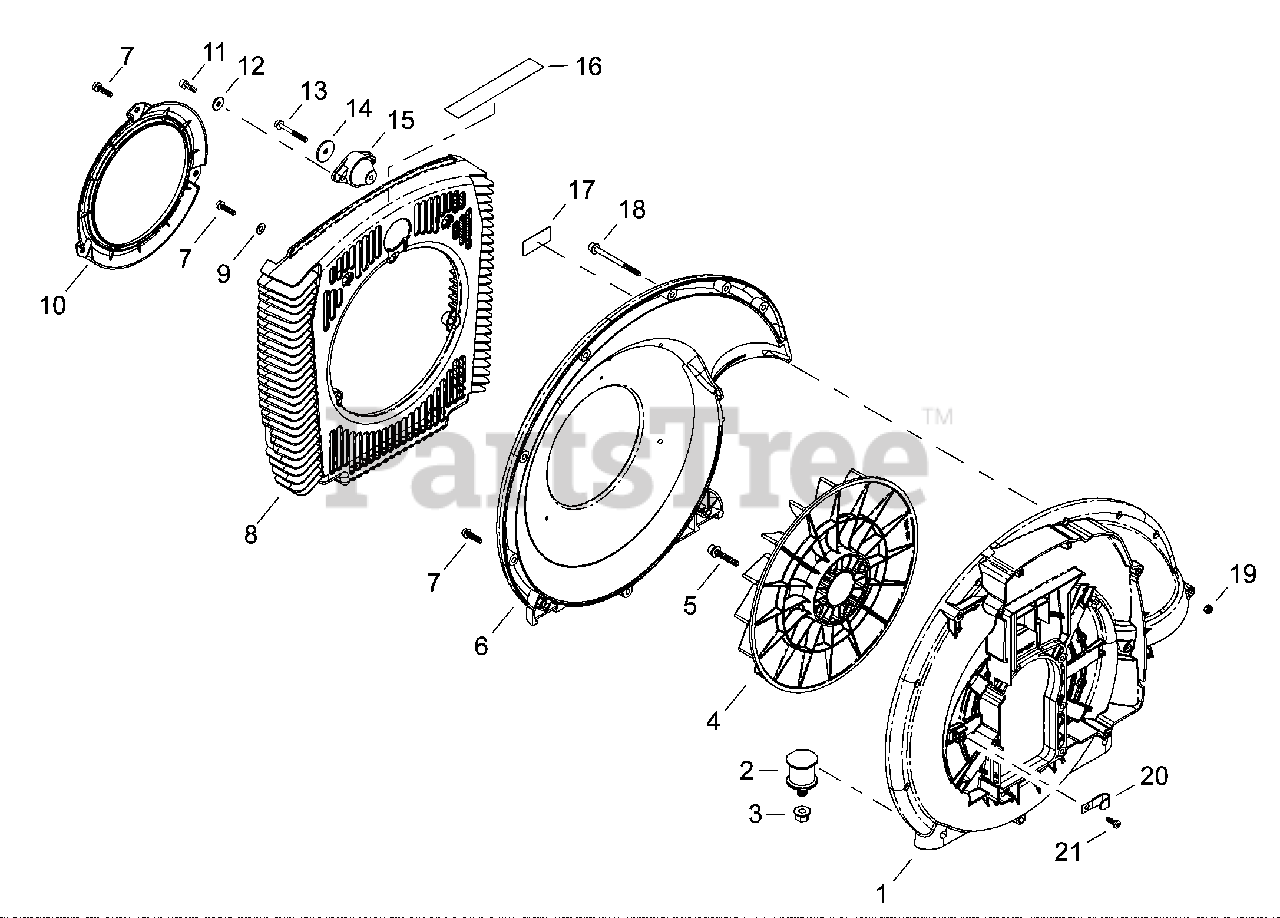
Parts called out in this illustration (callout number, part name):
1	COVER, FAN - OUTER
2	CUSHION
3	NUT - 6 -- FLANGE
4	IMPELLER
5	SCREW - 6X35
6	COVER, FAN - INNER
7	BOLT - 5X20
8	COVER, INTAKE
9	WASHER - 5
10	FUNNEL
11	SCREW - 5X16
12	COLLAR
13	BOLT - 5 -- TAPPING
14	COLLAR - 25X5.5X2
15	CUSHION
16	LABEL - CAUTION
17	LABEL - CAUTION
18	SCREW - 5X70
19	NUT - 5
20	CLAMP
21	SCREW - 5X14 -- TAPPING
